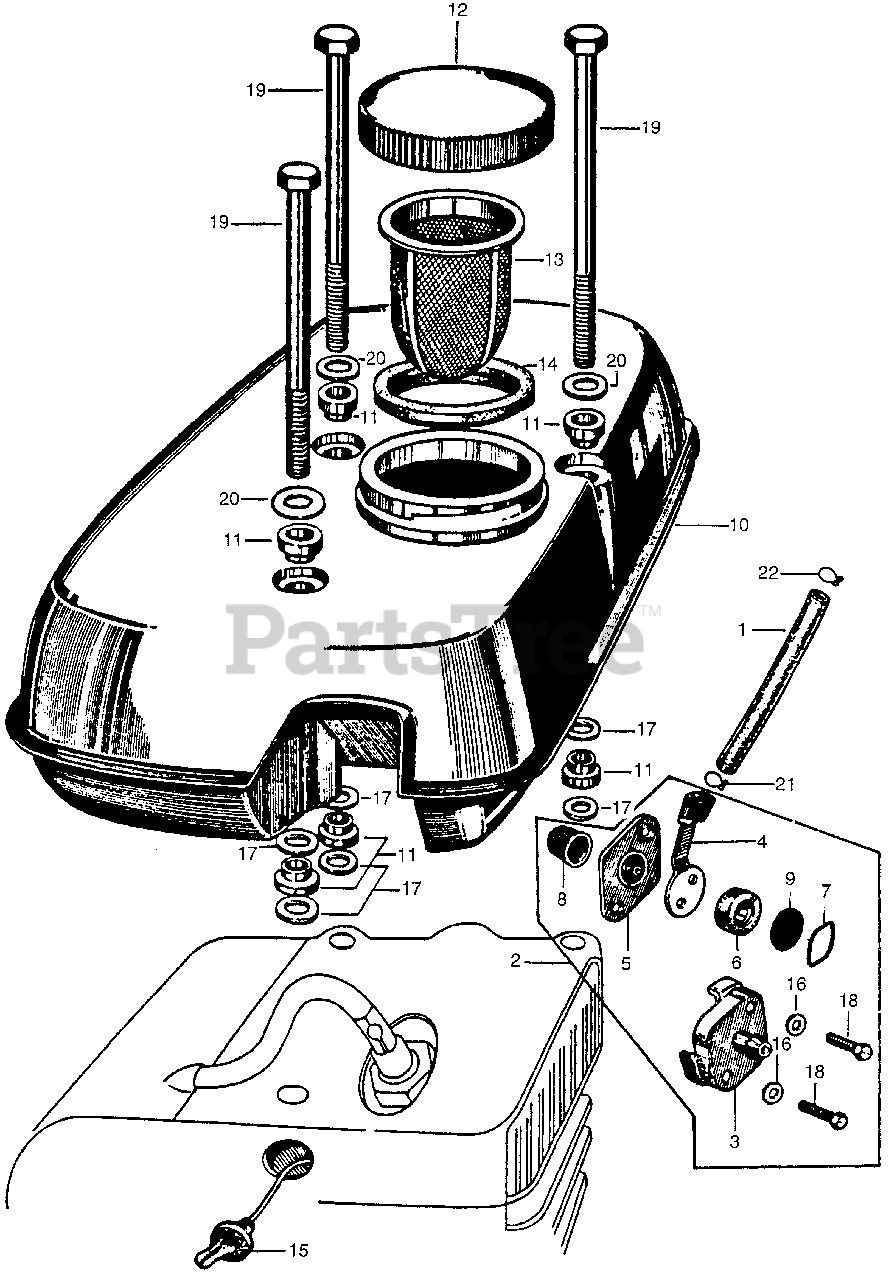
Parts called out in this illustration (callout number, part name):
1	TUBE, FUEL (NOT AVAILABLE)
1	TUBE, FUEL
2	PETCOCK ASSY. (N/A: SEE COMPONENTS)
3	BODY, PETCOCK
4	LEVER, PETCOCK
5	GASKET A, PETCOCK (NOT AVAILABLE)
6	GASKET B, PETCOCK (NOT AVAILABLE)
7	SPRING, PETCOCK LEVER (NOT AVAILABLE)
8	FILTER A, CHECK (NOT AVAILABLE)
9	FILTER B, CHECK
10	TANK, FUEL *PB1* (DARK BLUE)
11	INSULATOR, TANK
12	CAP, FUEL TANK
13	FILTER, FUEL
14	GASKET, FILTER
15	SWITCH ASSY., ENGINE
16	GASKET, FIBER (6MM)
17	WASHER A, INSULATOR
18	BOLT, HEX. (6X22)
19	BOLT, HEX. (10X160) (NOT AVAILABLE)
20	WASHER, PLAIN (10MM)
21	CLIP, TUBE (C9)
22	CLIP, TUBE (C12)
